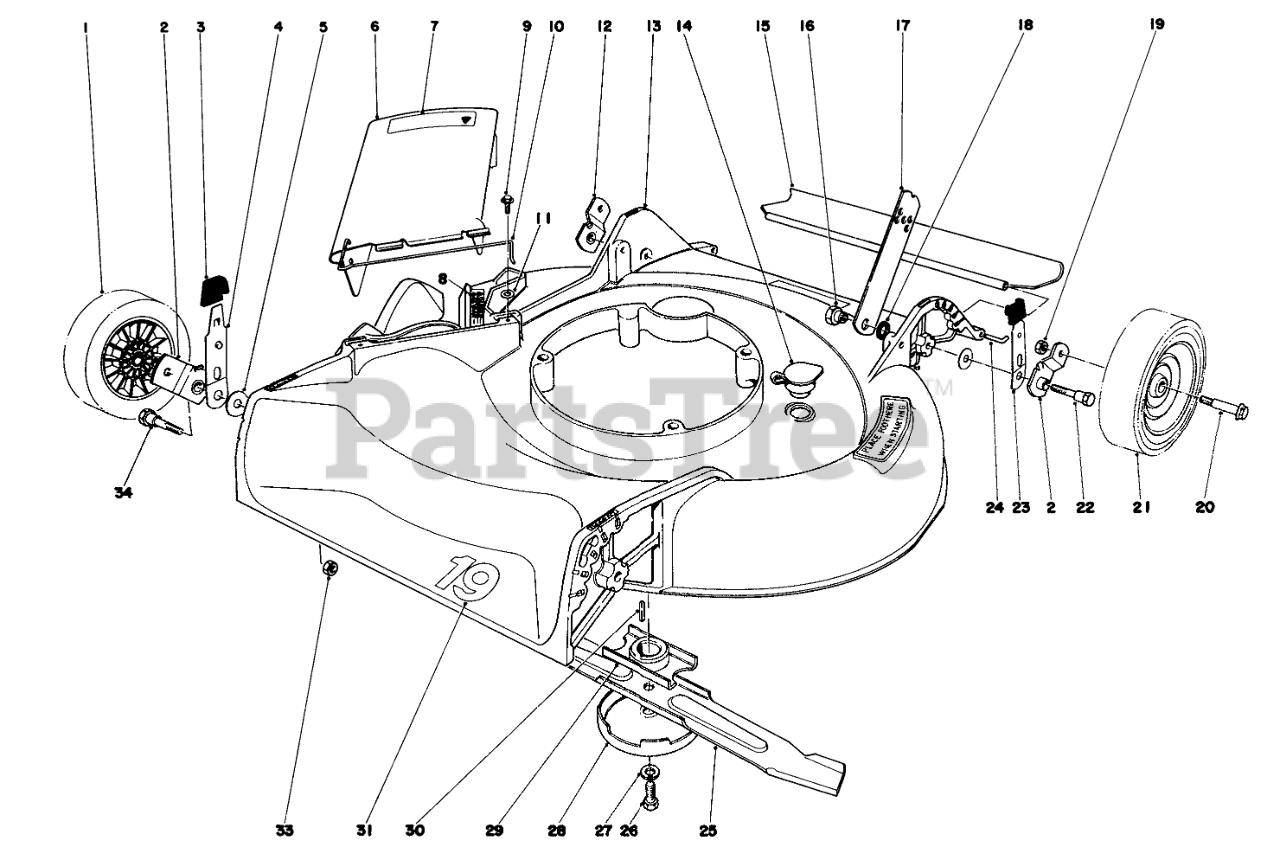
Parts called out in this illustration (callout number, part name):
1	Wheel Assembly
2	Pivot Arm
3	KNOB-ARM
4	SPRING ARM ASM
5	WASHER-PIVOT
6	Deflector-Cover Assembly(Incl. Ref. #7 & 10)
7	Decal-Caution (German)
8	Decal-Danger (German)
9	SCREW
10	SPRING HINGE
11	WASHER-FLAT
12	Pivot Arm
13	Housing
14	WASHOUT PLUG
15	Rear Shield
16	HANDLE PIVOT NUT
17	Handle Latch
18	HANDLE LATCH SPACER
19	Nut
21	Wheel Assembly
22	PIVOT SCREW
23	SPRING ARM ASM
24	SHIELD ROD
25	Blade
26	SPECIAL SCREW
27	WASHER-LOCK
28	Anti Scalp Cup
29	Blade Retailer
30	KEY-SQUARE
31	Decal-19"
33	Nut
34	PIVOT SCREW
